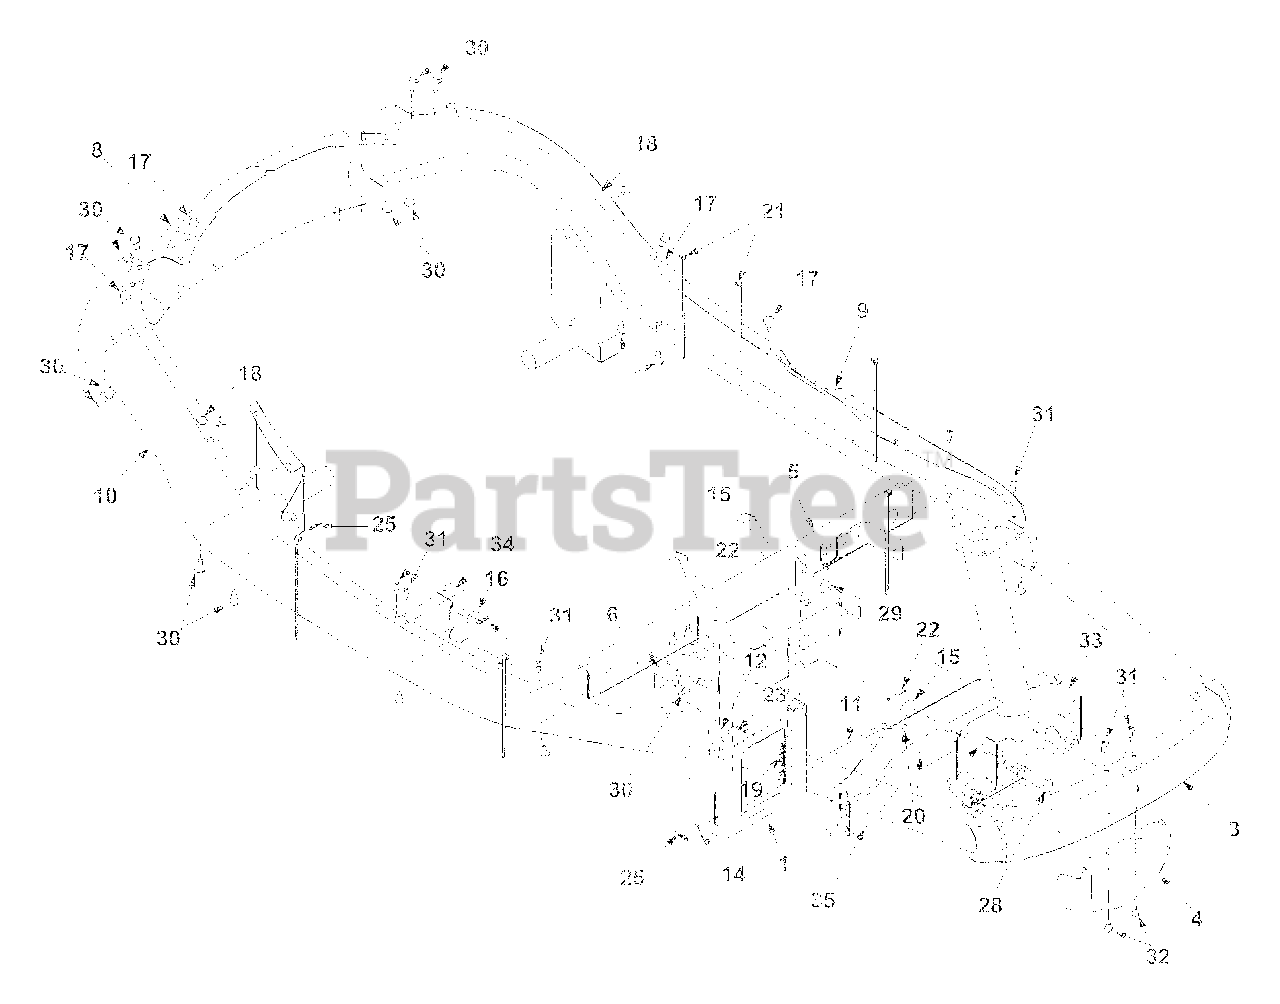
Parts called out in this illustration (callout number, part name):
12	Flat Washer .531 X 1.062 X .134
14	Flat Washer 5/16
15	Flat Washer .64 I.D. X 1.24 X .06
16	Flat Washer 3/8 X 1.00 X .030
17	Rubber Bumper
18	Rubber Bumper
19	Extension Spring
21	Cable Tie
22	Hairpin Clip
23	Hairpin Clip
25	Hairpin Clip
28	Clevis Pin
29	Lift Bracket Pin
30	TT Screw 5/16-18 x .75
31	Torx Mach. AB Scr. 1/4-14 x 0.625"
32	Hex TT Screw 1/4-20
33	Steering Support Bracket
34	Pivot Bracket Ass'y.: Hood
